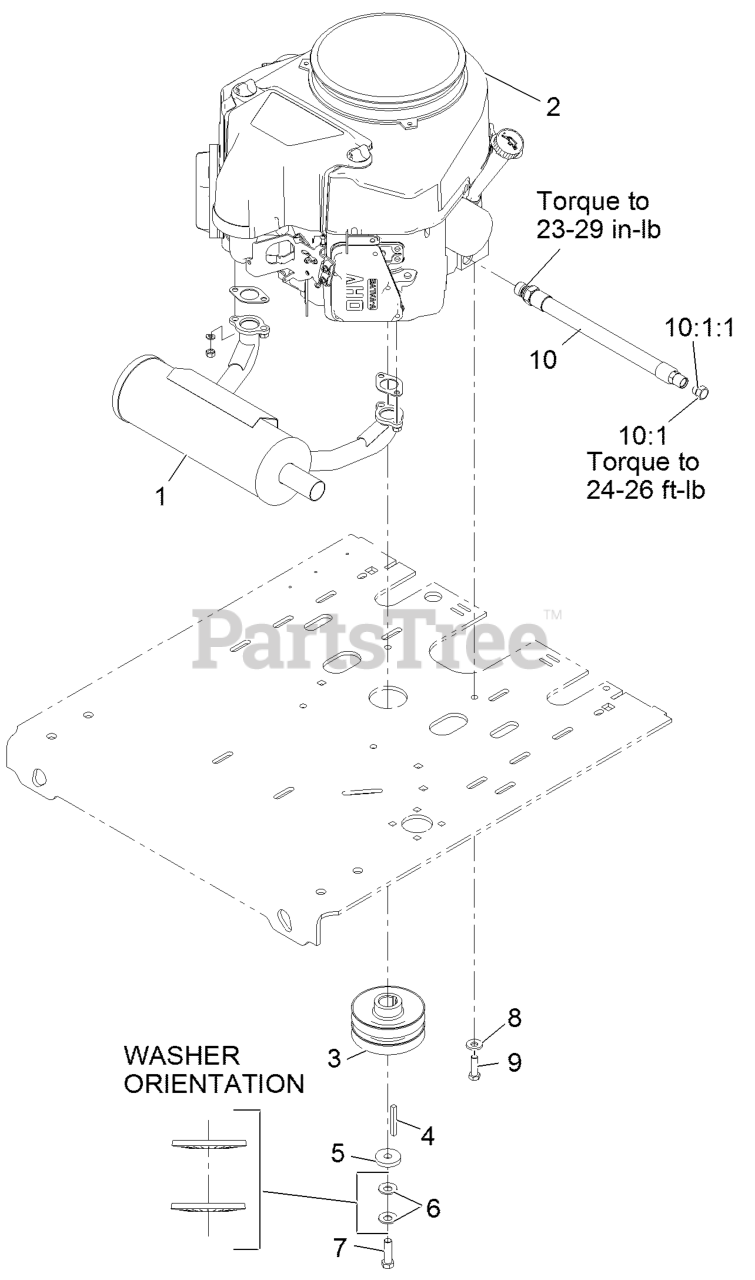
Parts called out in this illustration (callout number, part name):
1	MUFFLER-HORIZONTAL
2	Engine-Kaw Fs481V, Es
5	WASHER-CLUTCH
6	WASHER-SPRING
7	SCREW-HH 7/16-20 X 1 1/2 W/LOCTITE
8	WASHER-BELLEVILLE
9	SCREW-HH
10	ENGINE OIL DRAIN HOSE ASM
10:1	PLUG-HH
10:1:1	O-RING
